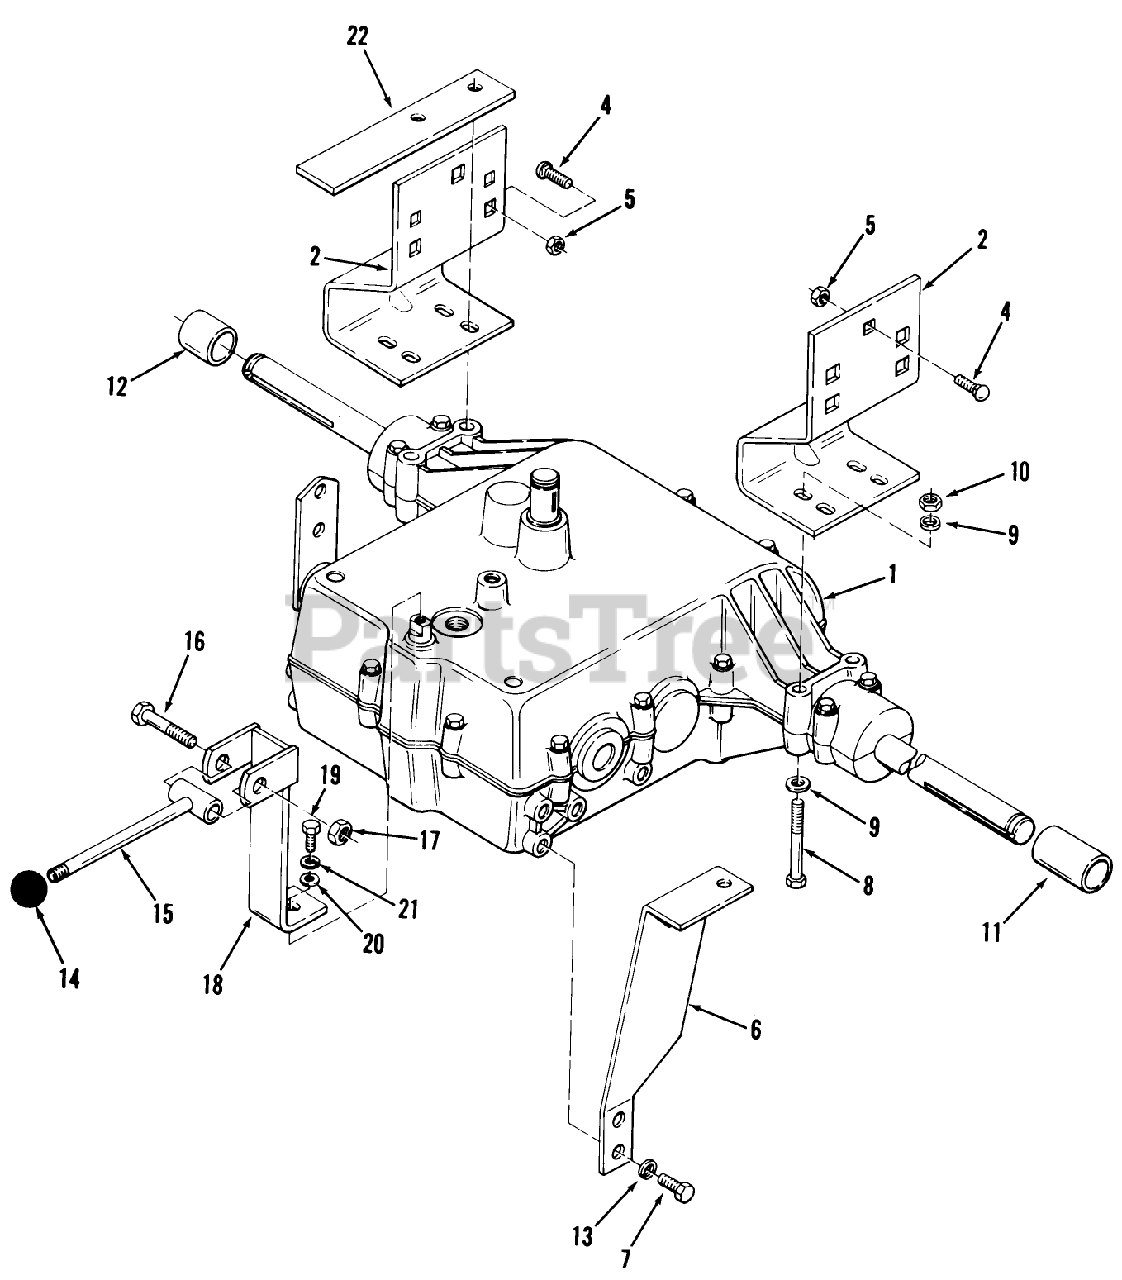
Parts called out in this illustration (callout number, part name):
1	ORDER FROM PEERLESS
4	CARRIAGE BOLT -4
6	TORQUE STRAP
7	Screw
9	WASHER 5/16 SAE
13	Lockwasher 5/16
15	ASSY-UP SHIFT ROD
20	WASHER
